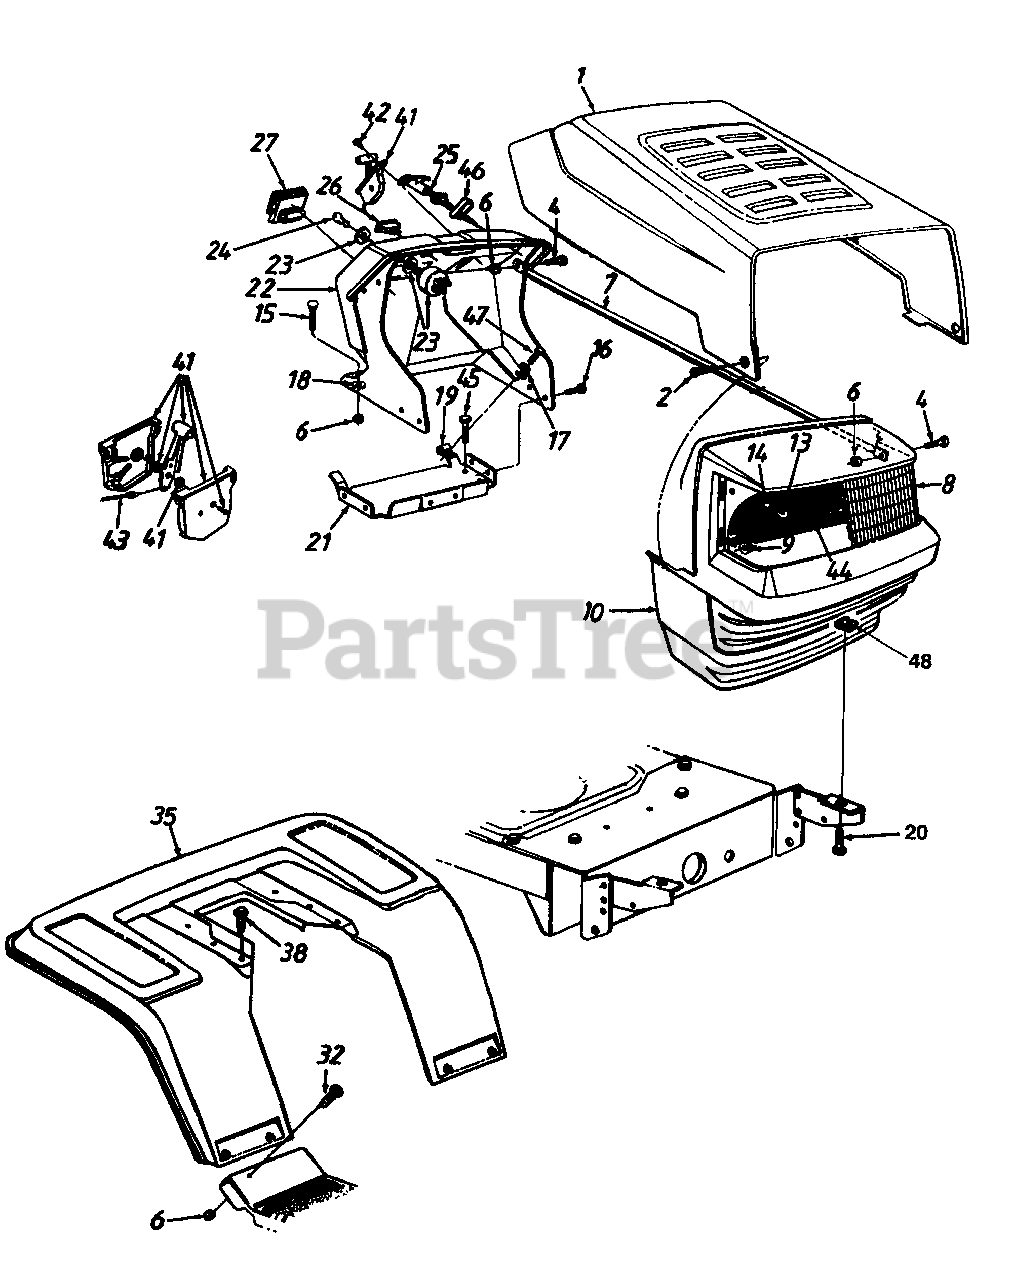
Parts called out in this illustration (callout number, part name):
4	Hex Bolt 1/4-20 x .62" Lg.
6	Hex Sems Nut 1/4-20 Thd.
8	Headlight Lens
9	Flange L-Nut 1/4-20 Thd.
10	Grille
13	Lamp
14	Socket
15	Carriage Bolt 1/4-20 x .75" Lg.
16	Hex Wash. Hd. TT-Tap Scr. 1/4-20 x .5" Lg.
17	Fl-Wash. .281" I.D. x .73" O.D.
18	Bolt Retainer 1/4" I.D.
19	Speed Nut 1/4-20 Thd.
20	Hex Bolt 5/16-18 x .75" Lg.
23	Ignition Switch
24	Ignition Key
25	Choke Control
26	Light Switch
27	Ammeter
32	Truss Mach. Scr. 1/4-20 x .5" Lg.
41	Throttle Box Ass'y.
42	Truss Mach. AB-Tap Scr. #10 x .5" Lg.
43	Throttle Control Wire
44	Grille Reflector Label
45	Hex Wash. Hd. B-Tap Scr. 5/16-18 x .5" Lg.
46	Choke Retainer
47	Hex TT-Tap Scr. 1/4-20 x .75" Lg.
48	U-Nut 5/16-18 Thd.
